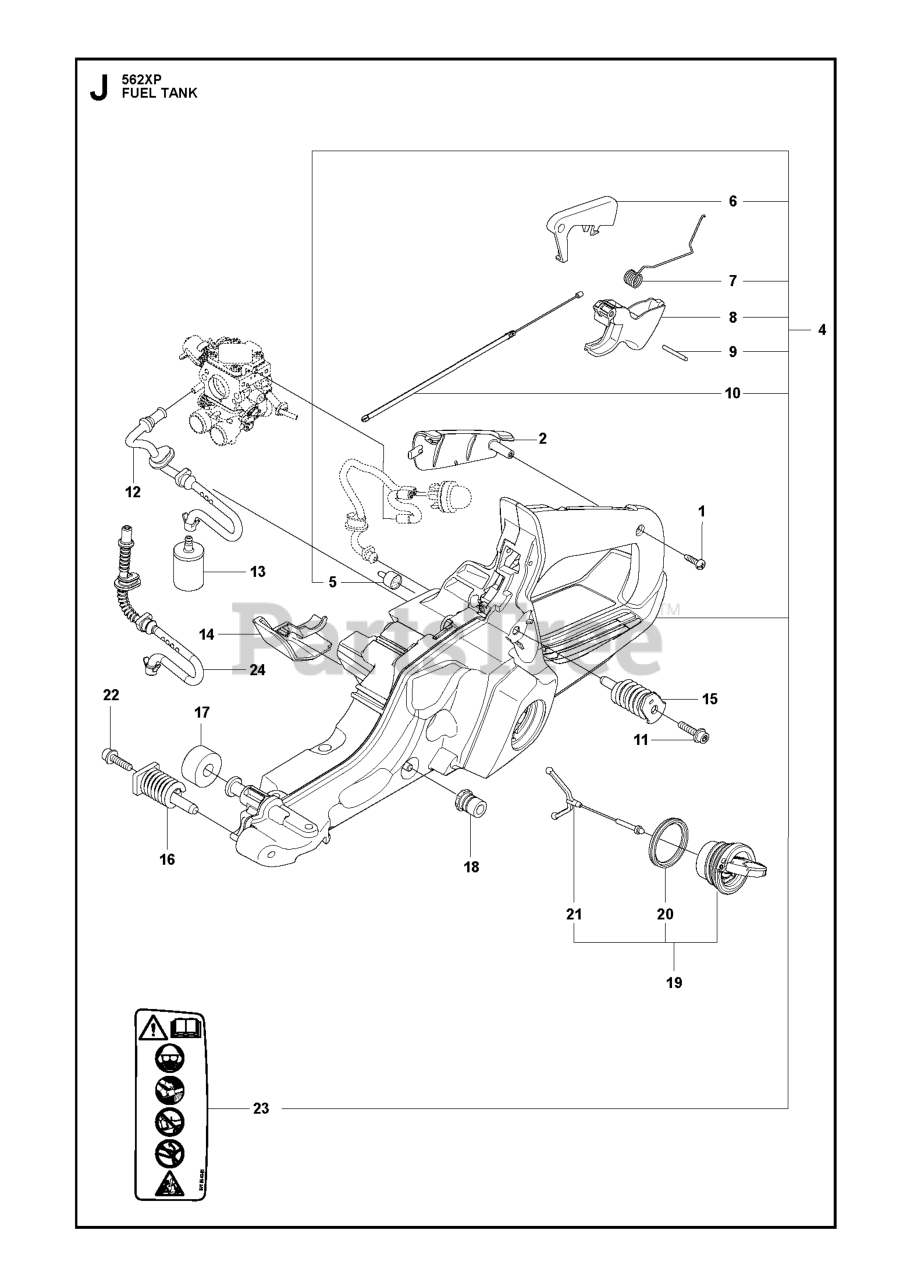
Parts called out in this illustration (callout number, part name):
1	SCREW CITXPANT
2	HANDLE INSERT
4	FUEL TANK ASSY
5	FUEL TANK VENT
6	THROTTLE LOCKOUT
10	THROTTLE CABLE ASSY
11	SCREW ITXSCFT
13	RP FUEL FILTER
14	COVER
15	ANTIVIBRATION ELEMENT REAR
16	ANTIVIBRATION ELEMENT FRONT
17	DEFLECTION LIMITER
18	LATERAL SUPPORT
19	TANK CAP ASSY
24	FUEL HOSE
